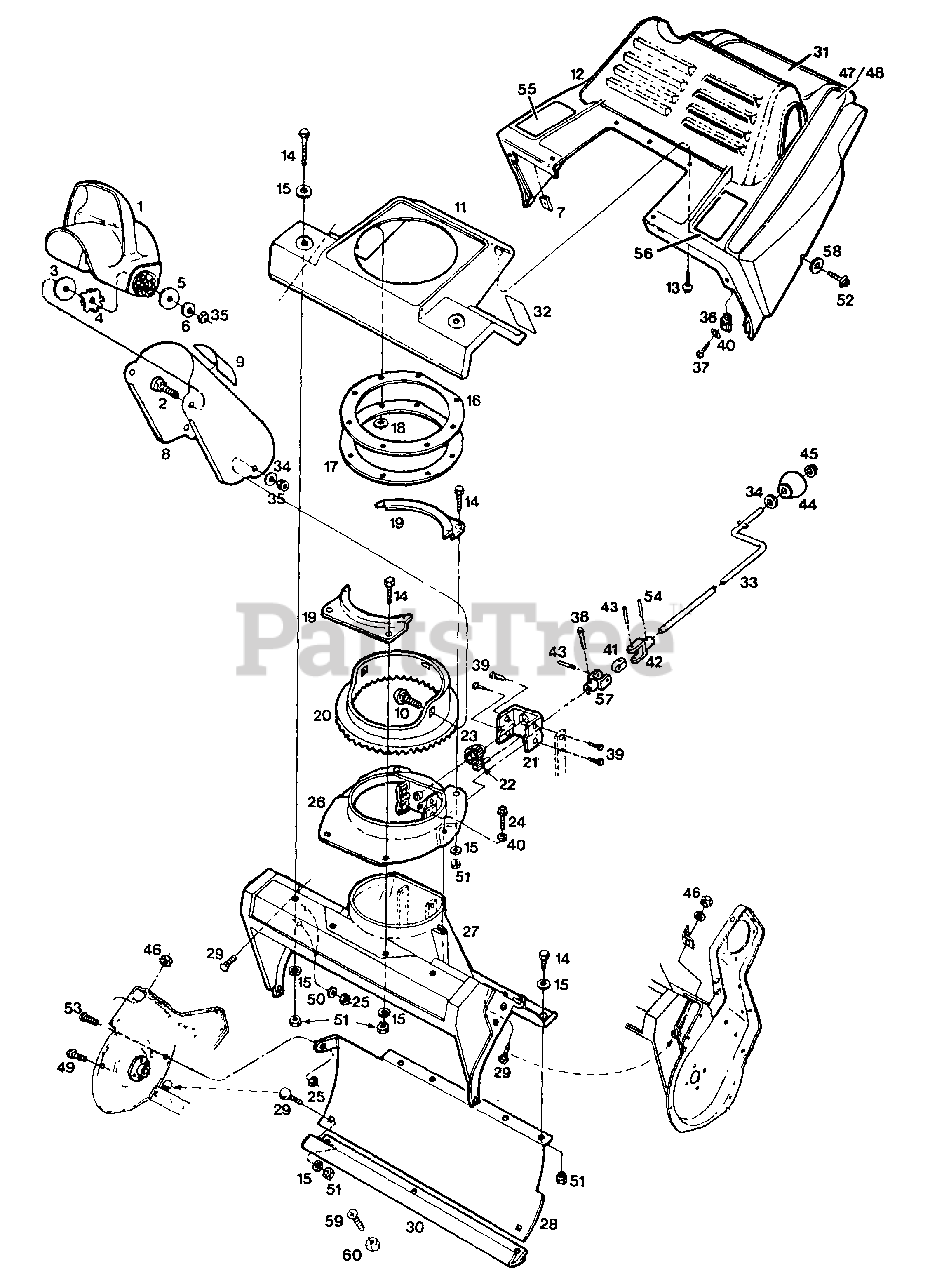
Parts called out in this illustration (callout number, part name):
1	DEFLECTOR - Chute
2	BOLT - Carriage 5/16 - 18 x 1
3	WASHER - Flat Rubber
4	WASHER - Octagon
5	WASHER - Flat 5/16
6	WASHER - Belleville
7	CLIP - U
8	CHUTE - Discharge
9	DECAL - Danger
10	BOLT - Carriage 5/16 - 18 x 5/8
11	COWLING - Transition
12	COVER - Engine
13	SCREW - Thread Form. #10 x 5/8
14	SCREW - Hex 1/4 - 20 x 3/4
15	WASHER - Flat 1/4
16	GASKET - Chute
17	RETAINER- Gasket
18	NUT - Push On
19	RETAINER
20	BASE - Chute
21	BRACKET - Gear
22	DRIVE - Gear
23	GEAR - Idler
24	SCREW - Plastite #12 - 14 x 1
25	NUT - #10-24 Nylock
26	PLATE - Chute Base
27	HOUSING - Auger
29	BOLT - Carriage 1/4 - 20 x 3/4
30	SCRAPER - Bar
31	DECAL - Console (Electric Start)
32	DECAL - Danger, Auger
33	HANDLE - Chute Rotate
34	WASHER - Flat 5/16
35	NUT, 5/16-18 Nylock
36	CLIP - U #10
37	SCREW - Hex #10 - 16 x 1-1/2
38	PIN - Cotter 1/8 Dia.
39	SCREW - Hex 1/4 - 20 x 5/8
40	WASHER - Flat #10
41	CONNECTOR - U-Joint
42	CLEVIS - U-Joint, Rear
43	PIN - Spiral
44	KNOB - Chute Rotate Handle
45	NUT - Pal 5/16
46	NUT - Keps 1/4 - 20
47	DECAL - Logo R.H.
48	DECAL - Logo L.H.
49	SCREW - Phillips 10 - 24 x 5/8
50	WASHER - Flat
51	NUT - Nylock 1/4 - 20
52	SCREW - Plastite 3/16 x 3/4
53	SCREW - Phillips #10 - 24 x 7/16
54	Pin - Roll
55	DECAL - Cover R.H.
56	DECAL - Cover L.H.
57	CLEVIS - U - Joint, Front
59	Screw Rd. Hd. 46-32 x 5/8"
60	Nut - Hex 46-32
